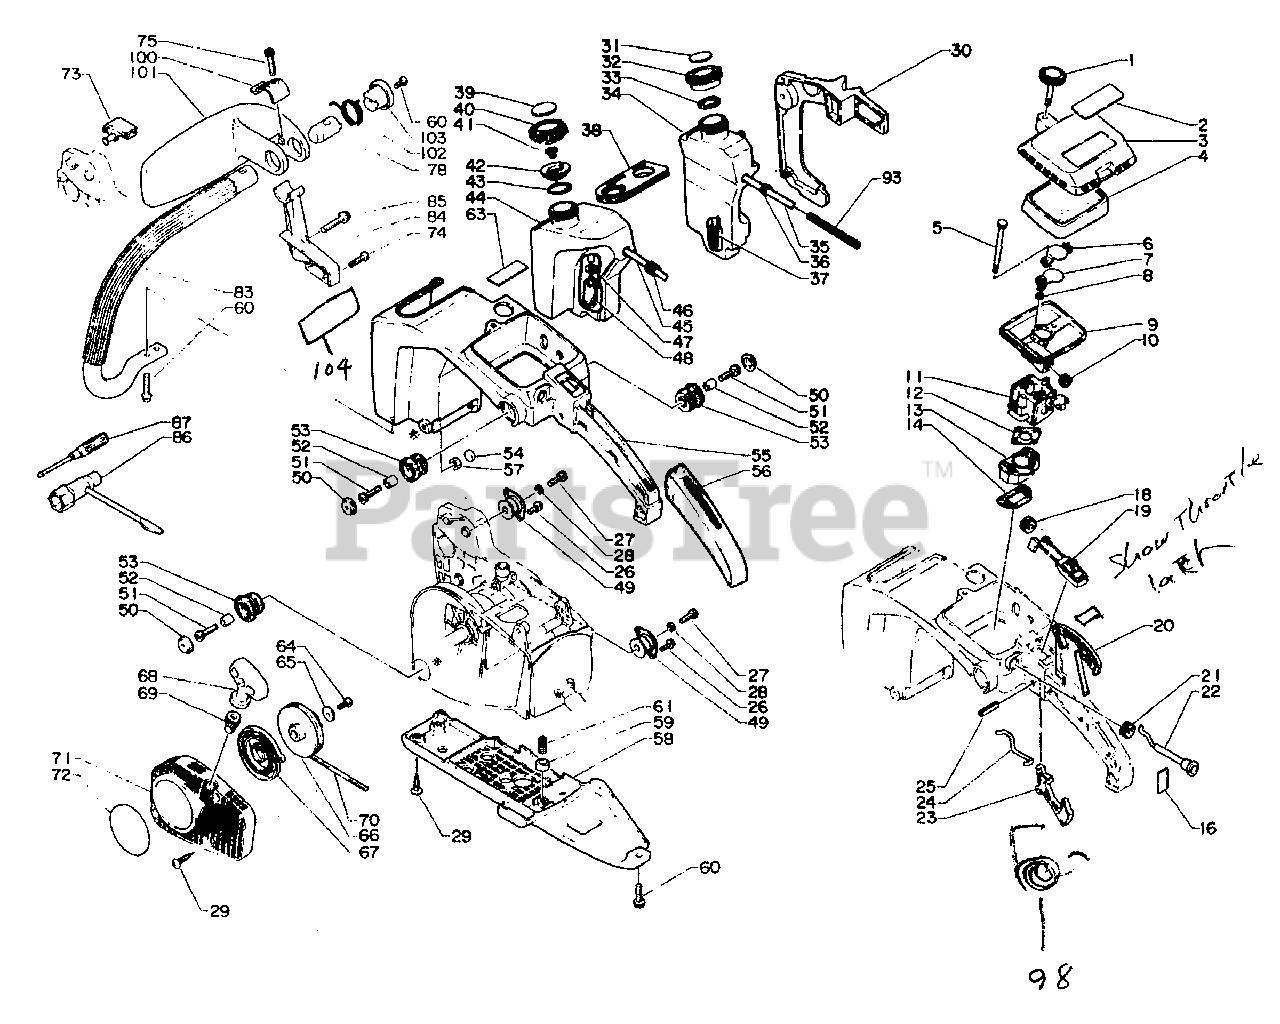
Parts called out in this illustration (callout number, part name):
1	THUMBSCREW
2	LABEL
3	COVER, AIR FILTER
4	FILTER, AIR
6	PLATE, PREVENT
7	SHUTTER, CHOKE
8	SPACER
9	CASE, AIR FILTER
11	CARBURETOR C1S-K3A
12	GASKET, INTAKE
13	INSULATOR, INTAKE
14	GASKET, INTAKE
16	LABEL - CHOKE
19	IGNITION SWITCH ASSY
20	LOCKOUT, THROTTLE
21	GROMMET
22	ROD, CHOKE
23	TRIGGER, THROTTLE
24	ROD, THROTTLE
25	PIN - SPRING -- 5X25
26	SCREW - 4X10
27	SCREW - 4X12
28	LOCKWASHER - 4
29	SCREW - 4X16 -- TAPPING
31	LABEL - CHAIN OIL
32	CAP, OIL TANK
33	GASKET, CAP
34	TANK, OIL
35	PIPE - OIL
36	GROMMET
37	FILTER, OIL
38	CONNECTOR
39	LABEL - FUEL MIX
40	CAP
41	VENT
42	HOLDER, VENT
43	O-RING - 22
44	TANK, FUEL
45	OIL PIPE KIT
47	WASHER - 5
48	FILTER, FUEL
49	CUSHION
50	CAP, CUSHION
51	SCREW - 4X20
53	CUSHION
54	SPACER
55	HANDLE - REAR
56	GRIP
57	NUT - 4
58	SUPPORT
59	BUSHING
60	SCREW - 5X20
61	SPRING
63	LABEL - NOISE
64	SCREW - 4X12
66	REEL, ROPE
67	SPRING, REWIND
68	GRIP, STARTER
69	GUIDE, ROPE
70	ROPE, STARTER - 3X850
71	CASE, STARTER
72	LABEL - ECHO
73	COVER
74	SCREW - 4X20 -- TAPPING
75	SCREW - 5X35
83	HANDLE - FRONT
84	SUPPORT
85	SCREW - 5X30
86	T-WRENCH - 10X19mm
87	SCREWDRIVER
98	SPRING, TRIGGER
101	GUARD
103	RETAINER
104	LABEL - KICK BACK
